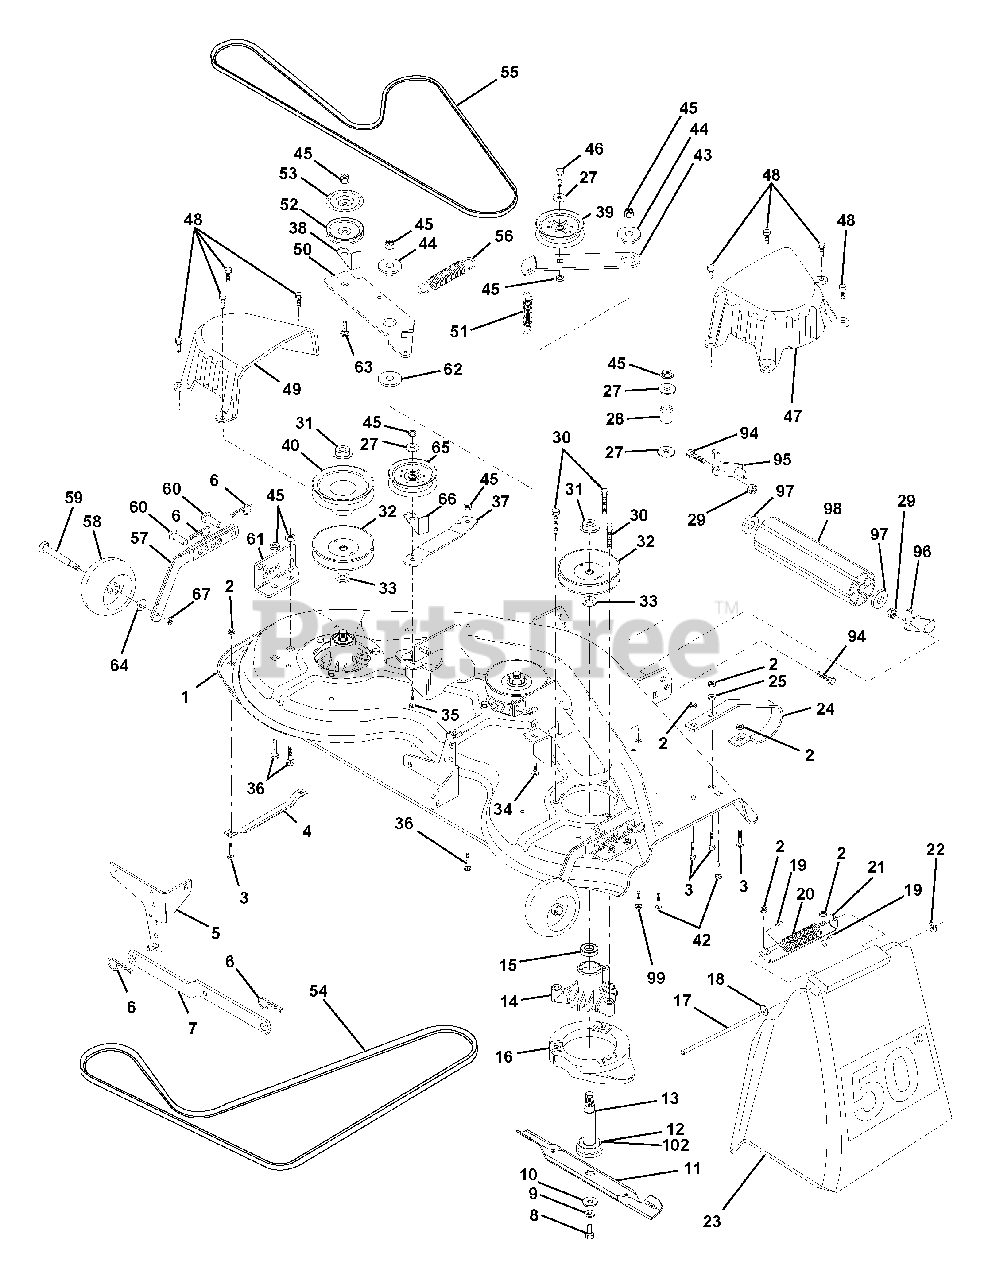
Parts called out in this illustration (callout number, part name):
1	Deck Asm., Mower 50" Vented
2	Nut, Crownlock 5/16-18 Unc
3	Bolt, Carriage 5/16-18 x 3/4
4	Runner, Mower LH
5	Bracket Asm., Sway Bar
6	Retainer, Spring
7	Arm Suspension, Rear
8	Bolt 3/8-24 x 1.25 Gr. 8 Patched
9	Washer, Lock Hvy 3/8 Unplated
10	Washer, Hard Blade Mower Vented
11	Blade (3 Required)
12	Bearing, Ball #6204 (Mandrel)
13	Shaft Asm., W/Lower Brg
14	Housing, Mandrel 50" Vent
15	Bearing, Ball Mandrel
16	Stripper, Mower Vented
17	Rod, Hinge
18	Washer 11/32 x 5/8 x 16 Ga.
19	Cap, Sleeve
20	Spring, Torsion Deflector
21	Bracket, Deflector
23	Shield, Deflector Mower
24	Runner, RH
25	Washer 11/32 x 3/4 x 16 Ga.
27	Washer 13/32 x 13/16 x 16 Ga.
28	Spacer, Spring Stop Idler
29	Nut, Lock Hex W/Wsh 3/8-16 Unc
30	Screw Thdrol Hex Head
31	Nut, Flg Top Lock Cntr 9/16
32	Pulley, Mandrel
33	Washer, Spacer Mower Vented
34	Bolt, Carriage 3/8-16 x 1-1/4
35	Bolt, Carriage 3/8-16 x 2
36	Bolt, Carriage 3/8-16 x 1 Gr. 5
37	Stiffener, Arm Idler
38	Keeper, Belt Idler
39	Pulley, Idler Flat
40	Pulley, Driven
42	Bolt, Carriage 5/16-18 Unc x 3/4
43	Arm, Idler Secondary
44	Spacer, Retainer
45	Nut, Crownlock 3/8-16 Unc
46	Bolt, Fin Hex 3/8-16 Unc x 1-3/4
47	Cover, Mandrel RH
48	Screw, Thd Roll 1/4-20 x 5/8
49	Cover, Mandrel LH
50	Arm, Idler Primary
51	Spring, Secondary
52	Pulley, Idler V Groove
53	Shield, Idler
54	V-Belt, Mower Primary
55	V-Belt, Mower Secondary
56	Spring, Primary
57	Bar Asm., Wheel Gauge
58	Wheel, Gauge
59	Bolt, Shoulder
60	Pin, Clevis
61	Bracket, Wheel Gauge
62	Washer Hardened
63	Bolt Carriage 3/8-16 x 1-1/2
64	Washer 3/8 x 7/8 x 14 Ga.
65	Pulley Idler Flat Mower
66	Keeper, Belt Idler 50" Vent
67	Nut, Center Lock 3/8-16
94	Bolt, Fin Hex 3/8-16 UNC x 1
95	Bracket, Asm. Noseroller LH
96	Bracket, Asm. Noseroller RH
97	Washer 17/32 x 7/8 x 16 Ga.
98	Roller, Nose
99	Bolt, Carriage 3/8-16 x 1-3/4 Gr. 5
102	Washer Felt
